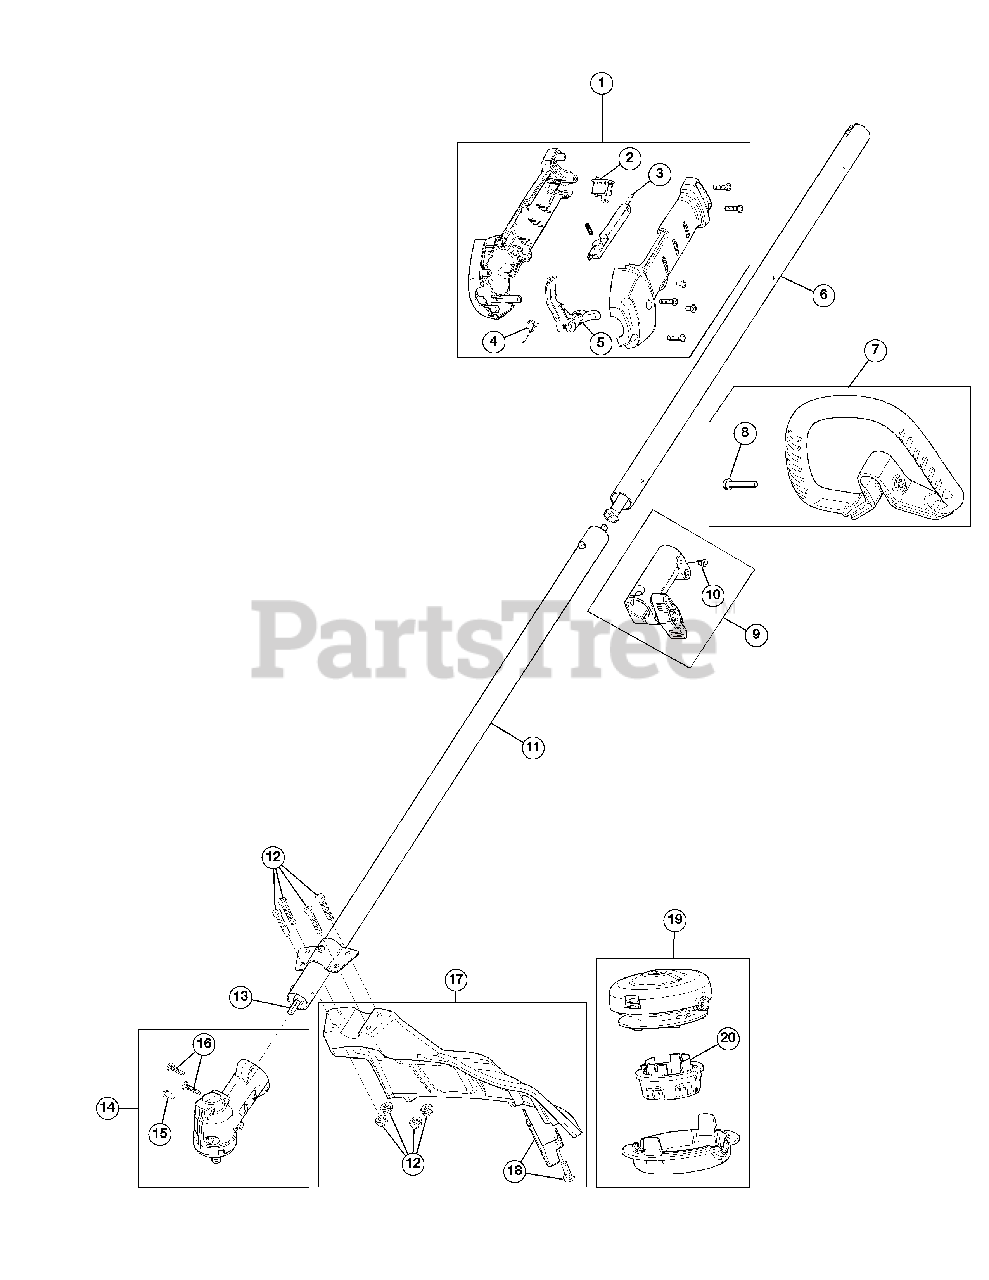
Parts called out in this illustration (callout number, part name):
1	Throttle Housing Assembly (Incl. 2 - 5)
2	Trigger Switch Assembly
3	Throttle Lock-out
4	Throttle Trigger Spring
5	Throttle Trigger
6	Upper Drive Shaft Assembly
7	D-Handle Assembly (Incl. 8)
9	Split Boom Coupler (Incl. 10)
10	Coupler Anti-Rotation Screw
11	Lower Drive Shaft Housing Assembly
12	Shield Mounting Screws and Nuts
13	Lower Flexible Drive Shaft
14	Gearbox Assembly (Incl. 15 - 16)
15	Gearbox Anti-Rotation Screw
16	Gearbox Mounting Hardware
17	Shield Assembly (Incl. 18)
18	Blade Assembly
19	Cutting Head Assembly (Incl. 20)
